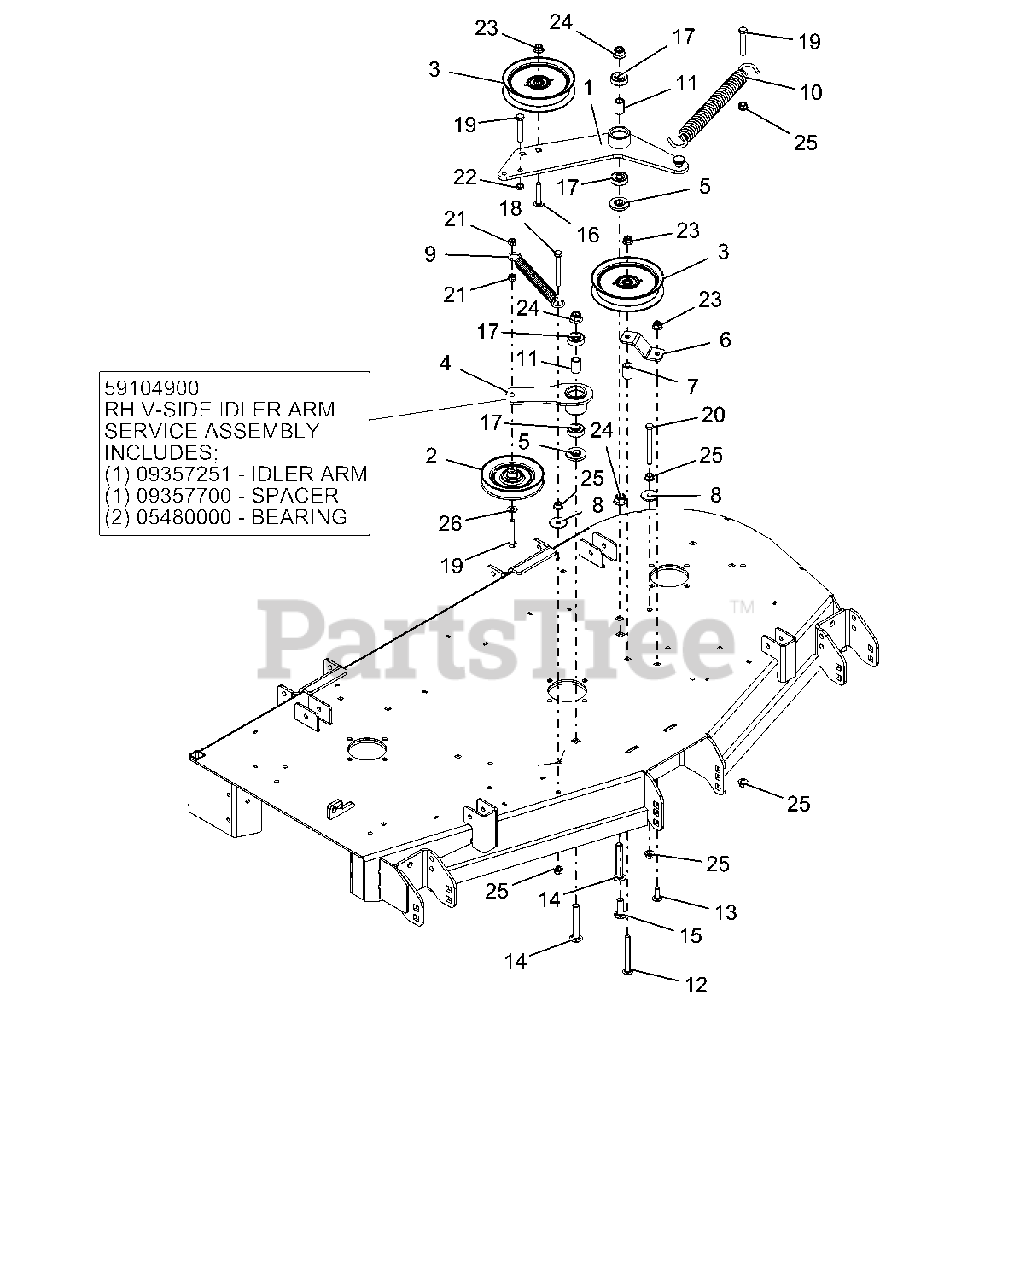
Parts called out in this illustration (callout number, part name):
1	WLDMT, DECK PTO IDLER ARM (BLACK)
2	IDLER, V-5.00" W/.69 STANDOFF
3	IDLER, FLAT - 5.00" X .75"
4	RH V-SIDE IDLER ARM SERVICE ASSEMBLY
4	IDLER ARM
4	SPACER
4	BEARING
4	WLDMT, DECK RH IDLER ARM-BLACK
5	SPACER, IDLER ARM
6	BRKT, PTO FIXED IDLER MTG (RED)
7	BUSHING, SLV .380 X .750 X 1.190
8	WSHR-FL-STL .406X1.375X.135 YZ
9	SPRG, EXTENSION - SWIVEL
10	SPRG, EXTENSION
11	SPACER, .510 X .750 X 1.148
12	BLT-RHDSSQNK .38-16X3.50 G5YZ
13	BLT-RDHDSHSQNK.38-16X1.0 G5YZ
14	BLT-RDHDSQSHNK .50-13X3.25 YWZC
15	BLT-RDHDSQSHNK .50-13X1.50 YWZC
16	BLT-RHDSSQNK .38-16X2.00 G5YZ
17	BRG-BALL .500X1.375X.44
18	BLT-HEX .38-16X3.00 GR5 YWZC
19	BLT-HEX .38-16X2.25 GR5 YWZC
20	BLT-HEX .38-16X3.50 GR5 YWZC
21	NUT-LK-CTR .38-16 YWZC
22	NUT, JAM .375-16 YWZC
23	NUT-LK-NYL-FLG .38-16 YWZC
24	NUT-LK-NYL-FLG .50-13 YWZC
25	@NUT-SPNLK-FLG .375-16 YWZC
26	WSHR-FL-STL.406X.812X.065 YWZ
